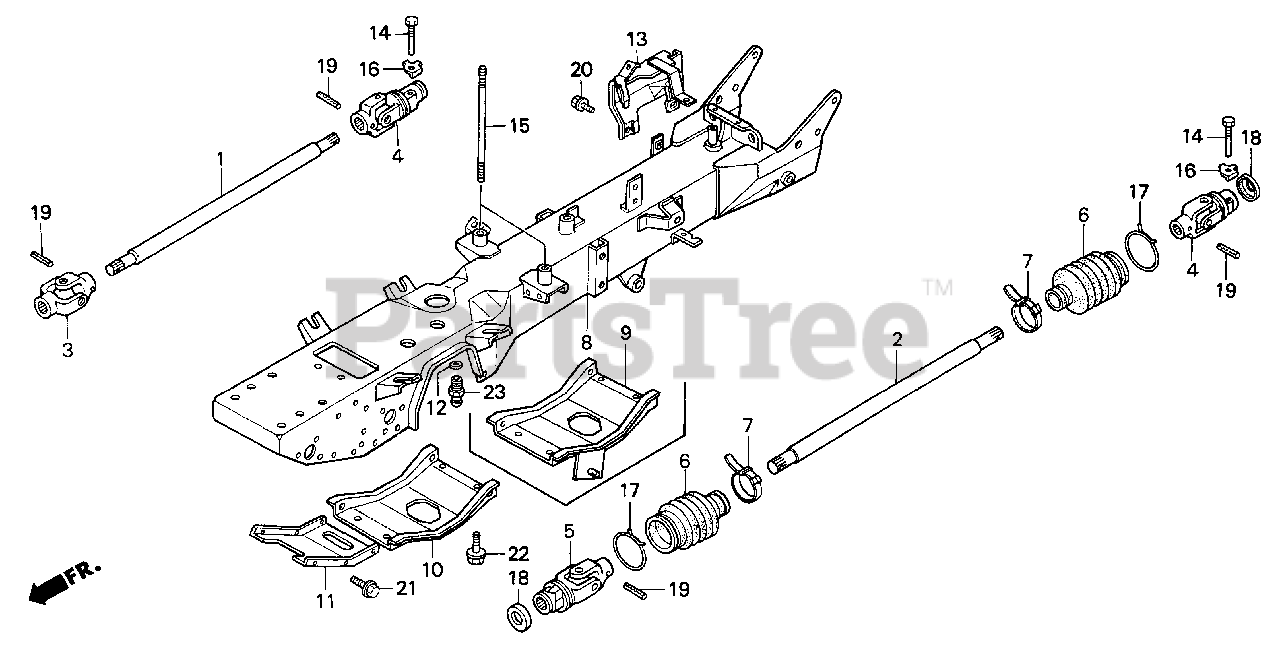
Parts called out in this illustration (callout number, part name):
1	SHAFT A, PROPELLER
2	SHAFT, PROPELLER (B)
3	JOINT B, UNIVERSAL
4	JOINT E, UNIVERSAL
5	JOINT F, UNIVERSAL
9	COVER A, FRAME (LOWER)
11	COVER B, FRAME (LOWER)
12	COLLAR (6.5X11X3)
13	COVER, RR. PROPELLER SHAFT
14	BOLT, SPECIAL (8MM)
15	BOLT, STUD (10X144)
16	WASHER, LOCK (8MM)
19	PIN, SPRING (6X32)
20	BOLT, FLANGE (6X12)
21	BOLT, FLANGE (8X16)
22	BOLT, FLANGE (10X20)
23	NIPPLE, GREASE (A.T6) (M6X1.0)
